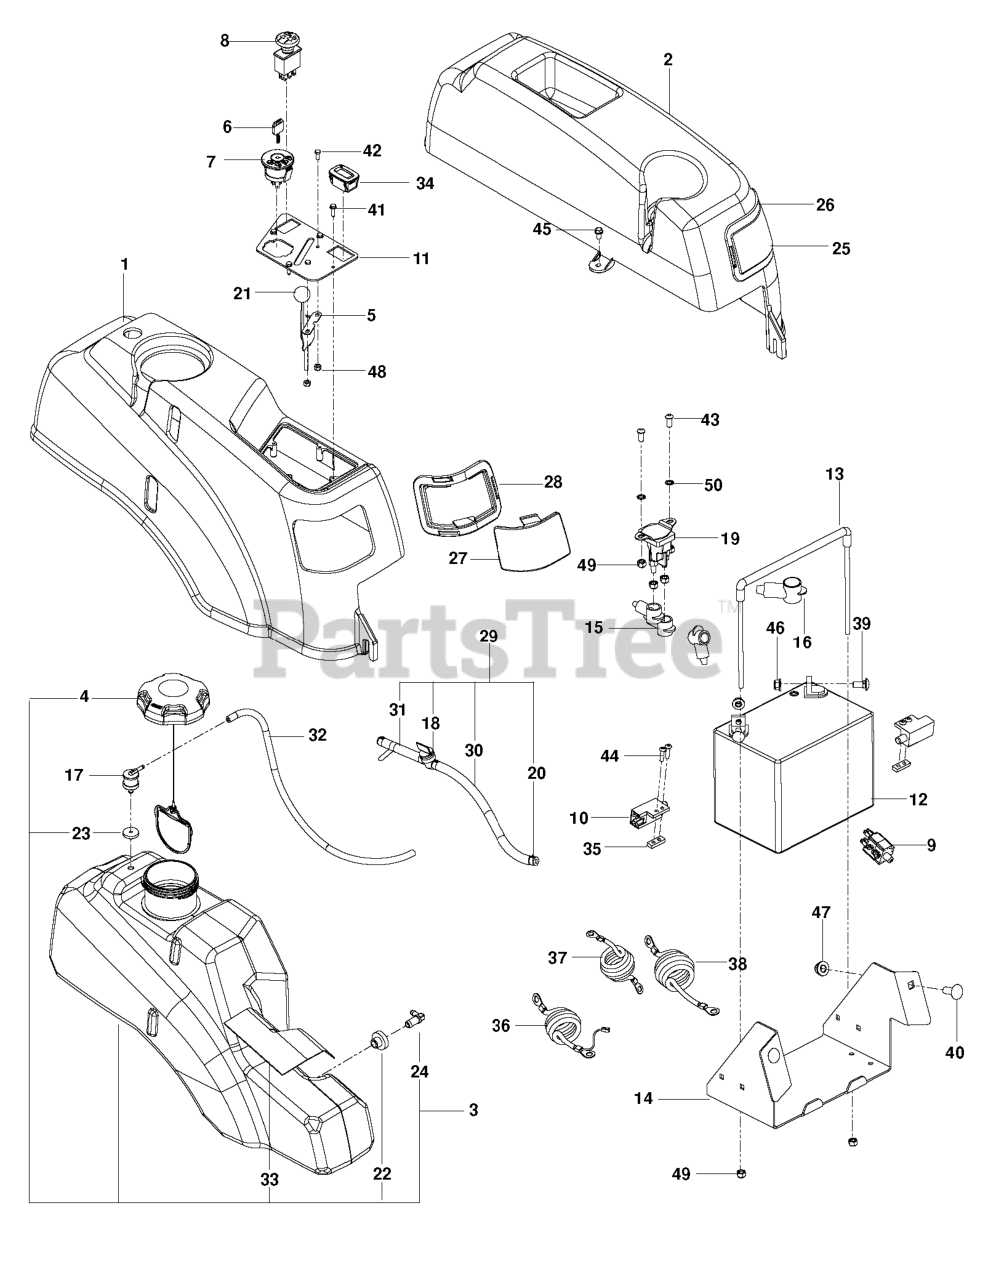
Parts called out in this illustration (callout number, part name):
1	FENDER RT, GRAY
2	FENDER, LT
3	TANK.FUEL.ASSEMBLY.LARGE
4	CAP, FUEL
5	THROTTLE CABLE
6	KEY MLD GEN DELTA
7	RP IGNITION SWITCH
8	RP SWITCH.PTO.8.TERMINAL.RED
9	SWITCH, BRAKE 3P
10	SWITCH INTERLOCKT
11	CONSOLE.PLATE.BLACK
12	BATTERY, 12 V 330 AMP
13	BATTERY TIE DOWN ASSEMBLY
14	BOX, BATTERY, BLACK
15	TERMINAL COVER-SM
17	VALVE.FUEL.CHECK
18	FUEL VALVE
19	SOLENOID.W/BRASS.PLUNGER
20	HOSE CLAMP
21	KNOB.ROUND.BALL.BLACK
22	RUBBER GROMMET
23	GROMMET, CHECK VALVE
24	STEM, FUEL TANK
25	LENS, COLORED LEFT
26	LEFT HEADLIGHT RIM GREY
27	LENS, COLORED RIGHT
28	RT HEADLIGHT RIM GREY
29	FUEL LINE ASSY
30	GAS LINE 10"
31	FUEL LINE 3"
32	HOSE, FUEL, 3/16" X 20"
33	SHIELD, HEAT
34	RP.GUAGE.SRVCMNDR.HRMTR.
35	TAPPED PLATE
36	CABLE POSITIVE LONG W/LEAD
37	CABLE POSITIVE, LONG
38	BATTERY CABLE, NEGATIVE
39	RP BOLT 5/16-18 X3/4 ZN/YEL GR
40	BOLT D
41	SCR #10-12X3/4 HEX WAS HD ZD
42	HCS #10-24 X 1/2
43	SCR 1/4-20 X 5/8 BTN SKT HD ZD
44	SCR #10-24 X .75 SKT HD BLK
45	SCREW
46	5/16-18 NYLOC FLANGE NUT
47	NUT 3/8-16 HEX FLG NYLOC ZD
48	NUT 10-24 NYLOC
49	NUT.1/4-20.HEX.NYLOC.ZD
50	WASHER 1/4 INT TOOTH
